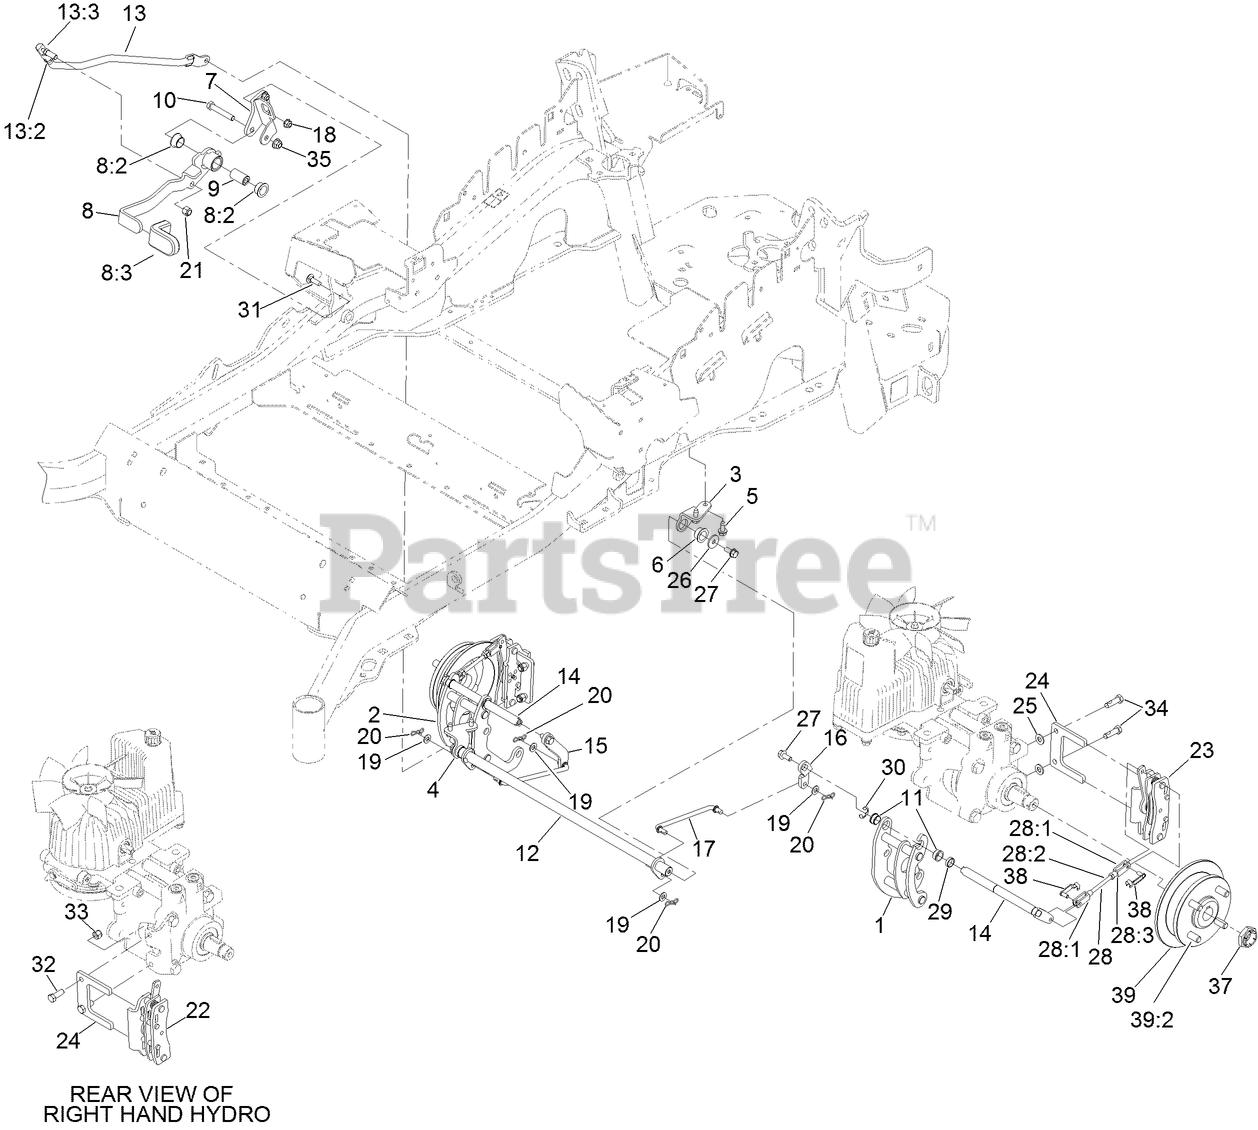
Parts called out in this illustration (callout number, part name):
1	MOUNT-BELLCRANK, LH
2	MOUNT-BELLCRANK, RH
3	MOUNT-PIVOT, LH
4	MOUNT-PIVOT, RH
5	SCREW-HWHTF
6	BUSHING-FLANGE
7	BRACKET-MOUNT
8	BRAKE LEVER ASM
8:2	BUSHING-FLANGE
8:3	GRIP-LEVER
9	HANDLE-PIVOT, BRAKE
10	SCREW-HH
11	BUSHING
12	SHAFT-CROSS
13	ASM, FRONT LINKAGE
13:2	END-TIE ROD, RH
13:3	NUT-HJ
14	BELLCRANK
15	ARM-INNER, RH
16	ARM-INNER, LH
17	LINK-MID
18	NUT-HF, NI
19	WASHER-PLAIN
20	PIN-COTTER, LOCKING
21	NUT-LOCK
22	CALIPER-BRAKE, RH
23	CALIPER-BRAKE, LH
24	PLATE-MOUNT, BRAKE
25	WASHER-FLAT
26	WASHER-FLAT
27	SCREW-HHF
28	REAR LINKAGE ASM
28:2	LINKAGE, REAR
28:3	NUT-JAM
29	SPACER
30	E-RING
31	BOLT-CARR
32	SCREW-HH,
33	NUT-LOCK
34	SCREW-HH, PATCH,
35	NUT-HF, NI
37	LOCKNUT
38	PIN-CLEVIS, SPRING
39	WHEEL HUB ASM
39:2	STUD-WHEEL
